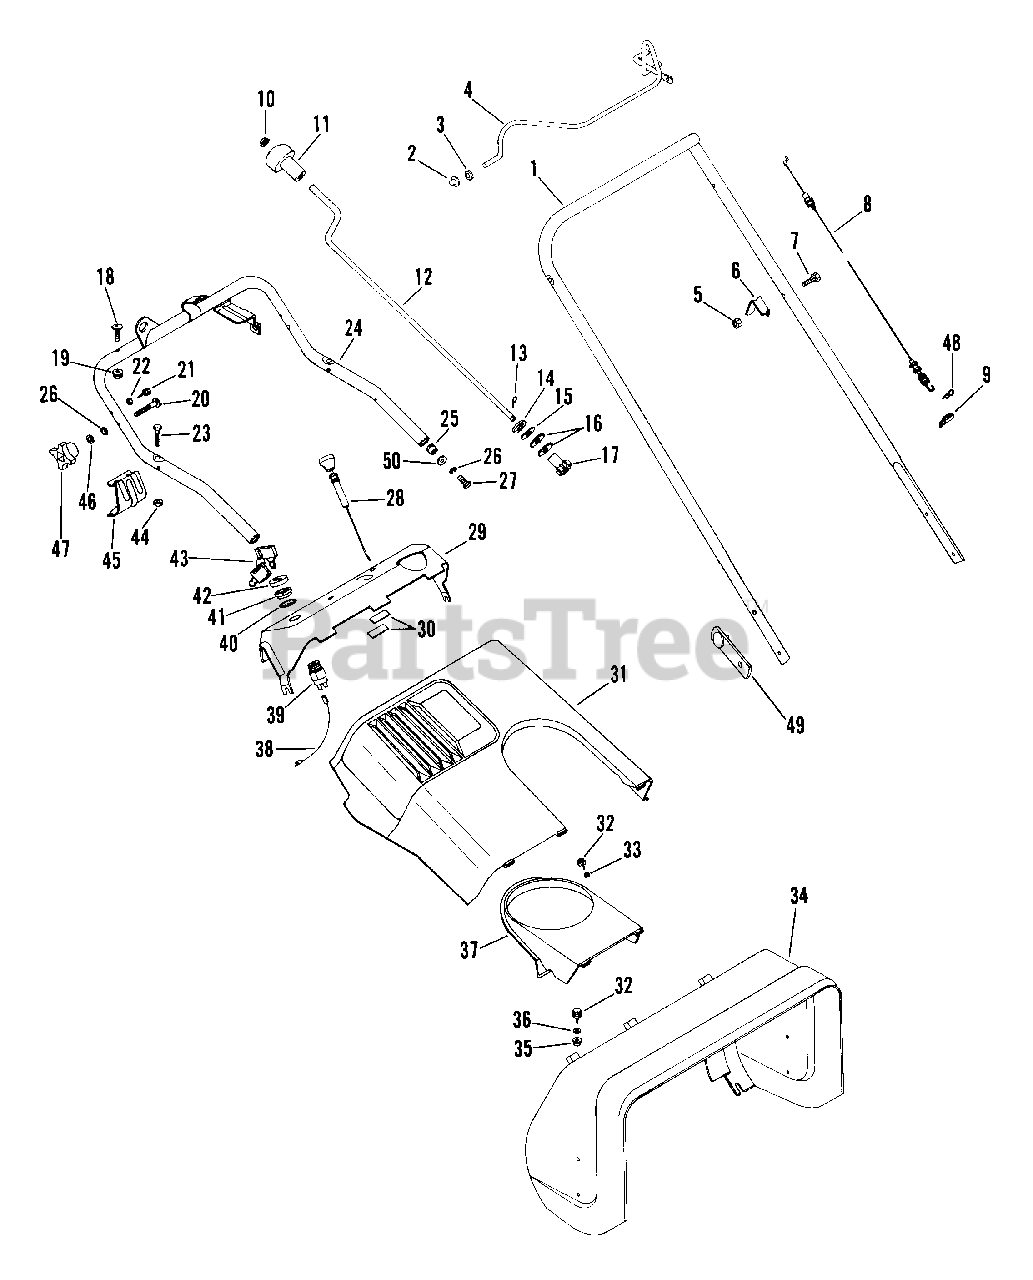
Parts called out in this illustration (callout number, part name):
1	UPPER HANDLEBAR
2	NUT-PUSH .312 DIA. PAL
3	WSHR-FL-STL .344X.688X.065 PL
4	BAIL
5	NUT-KEPS .250-20
6	CABLE ANCHOR-LH
7	BLT-RDHDSQNK .25-20X1.25 XLGPL
8	CONTROL CABLE
9	CABLE TIE LG 5-1/2
10	CAP, 3/8 ROD YWZC
12	CHUTE CRANK
13	PIN-HAIR INT .08X.38X1.42 YWZC
14	PUSHNUT .625
15	WAVE WASHER .640X.875X.125FH
16	WSHR-FL-STL .630X1.005X.062 PL
18	BLT-CRVD-HD .25-20X.25 PL
19	NUT-LK-FLG .250-20 PL
20	BLT-CRVD-HD .31-18X1.44 YWZC
21	SCR-TAP 10-16X.75 HWH PL AB
22	WSHR-FL-STL .194X.492X.047 PL
23	SCR-SKH .25-20X1.25 FLTCNTRSK
24	TUBE WELDMENT
25	TUBE-CONCTR .312-18
26	WSHR-LK .312X.097 PL HVY
27	BLT-HEX .31-18X1.25 PL GR2
28	CHOKE CONTROL
29	DASH W/DECAL
30	CATCH ASSEMBLY
31	ENGINE COVER
32	SCR-TAP 10-12X.50 CRPH PL A BL
33	WSHR-FL-STL .215X.56X.085 PL
34	AUGER COVER W/DECALS
35	PLASTIC GROMMET
36	WSHR-FL-STL .219X.500X.049 PL
39	KEY SWITCH ASSEMBLY
40	WSHR-LK-INT .625X.045 PL
41	NUT-PANEL .625-32 GRECO
42	CAP - IGNITION SWITCH
43	KEY SET
44	NUT-LK-CTR .250-20 PL
45	SWITCH BRACKET WELDMENT
46	WSHR-FL-STL .323X.625X.062 PL
47	KNOB 5/16-18 UNC
48	PIN-HAIR INT .06X.18X.77
49	STRAP ASSEMBLY
50	WSHR-FL-STL .328X.875X.062 PL
